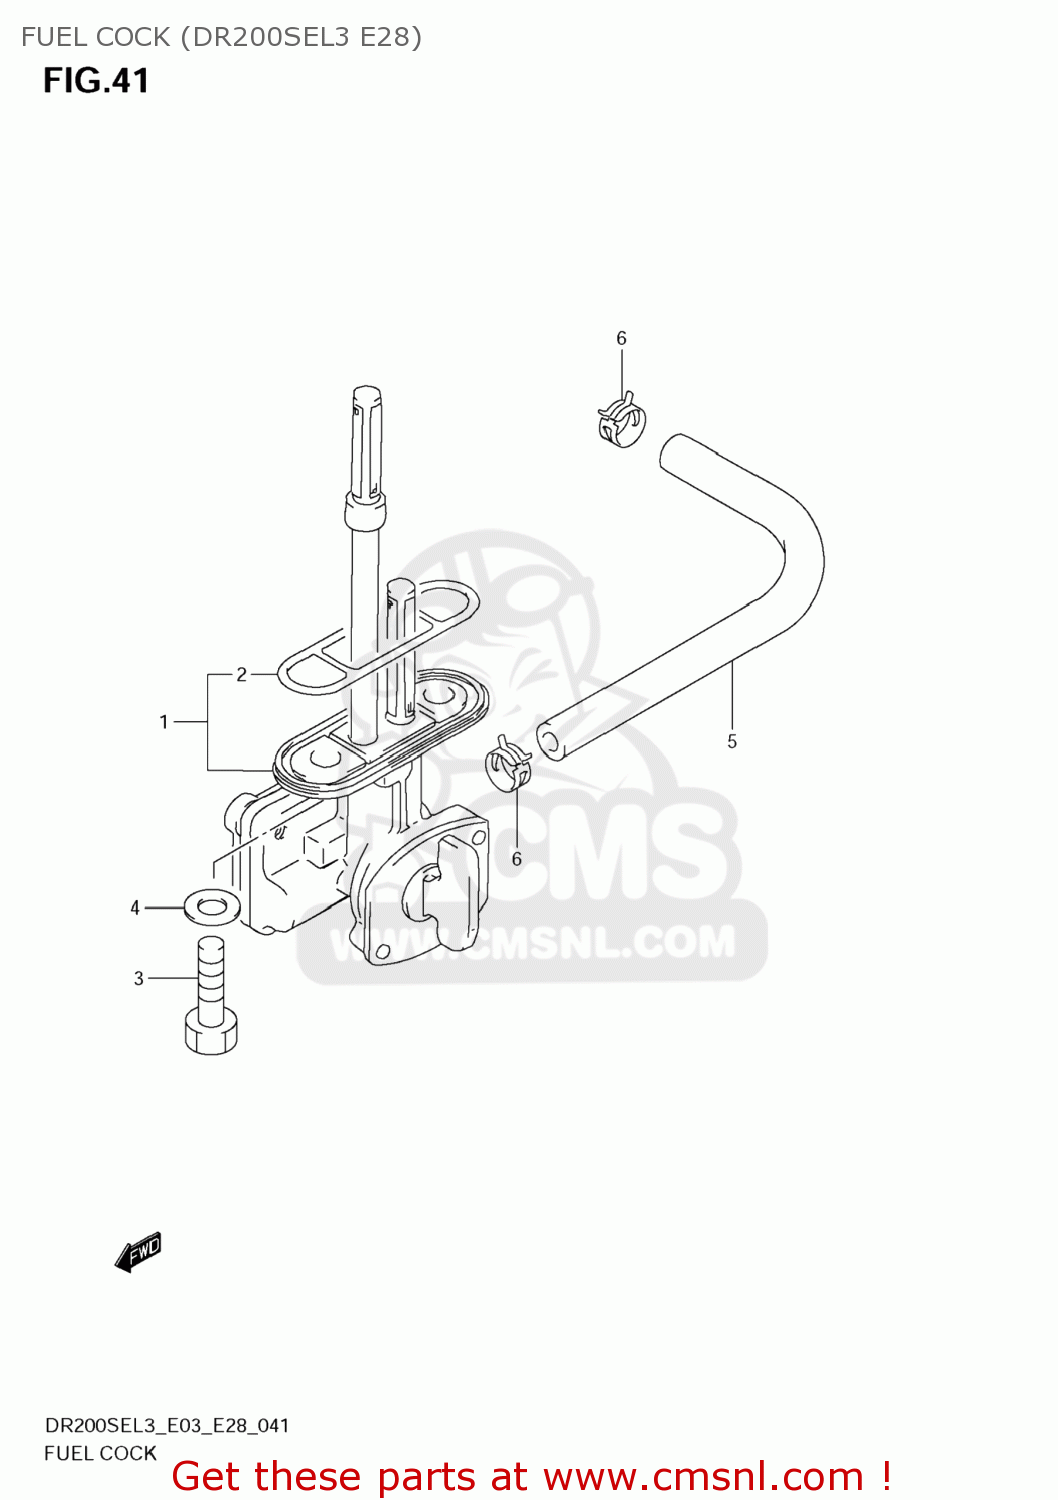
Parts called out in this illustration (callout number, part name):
1	COCK ASSY,FUEL
2	GASKET,JOINT (NAS)
3	BOLT(6X20)
4	GASKET(6.4X11.5X0.8) (NAS)
5	HOSE(5X10X160)
6	CLIP
